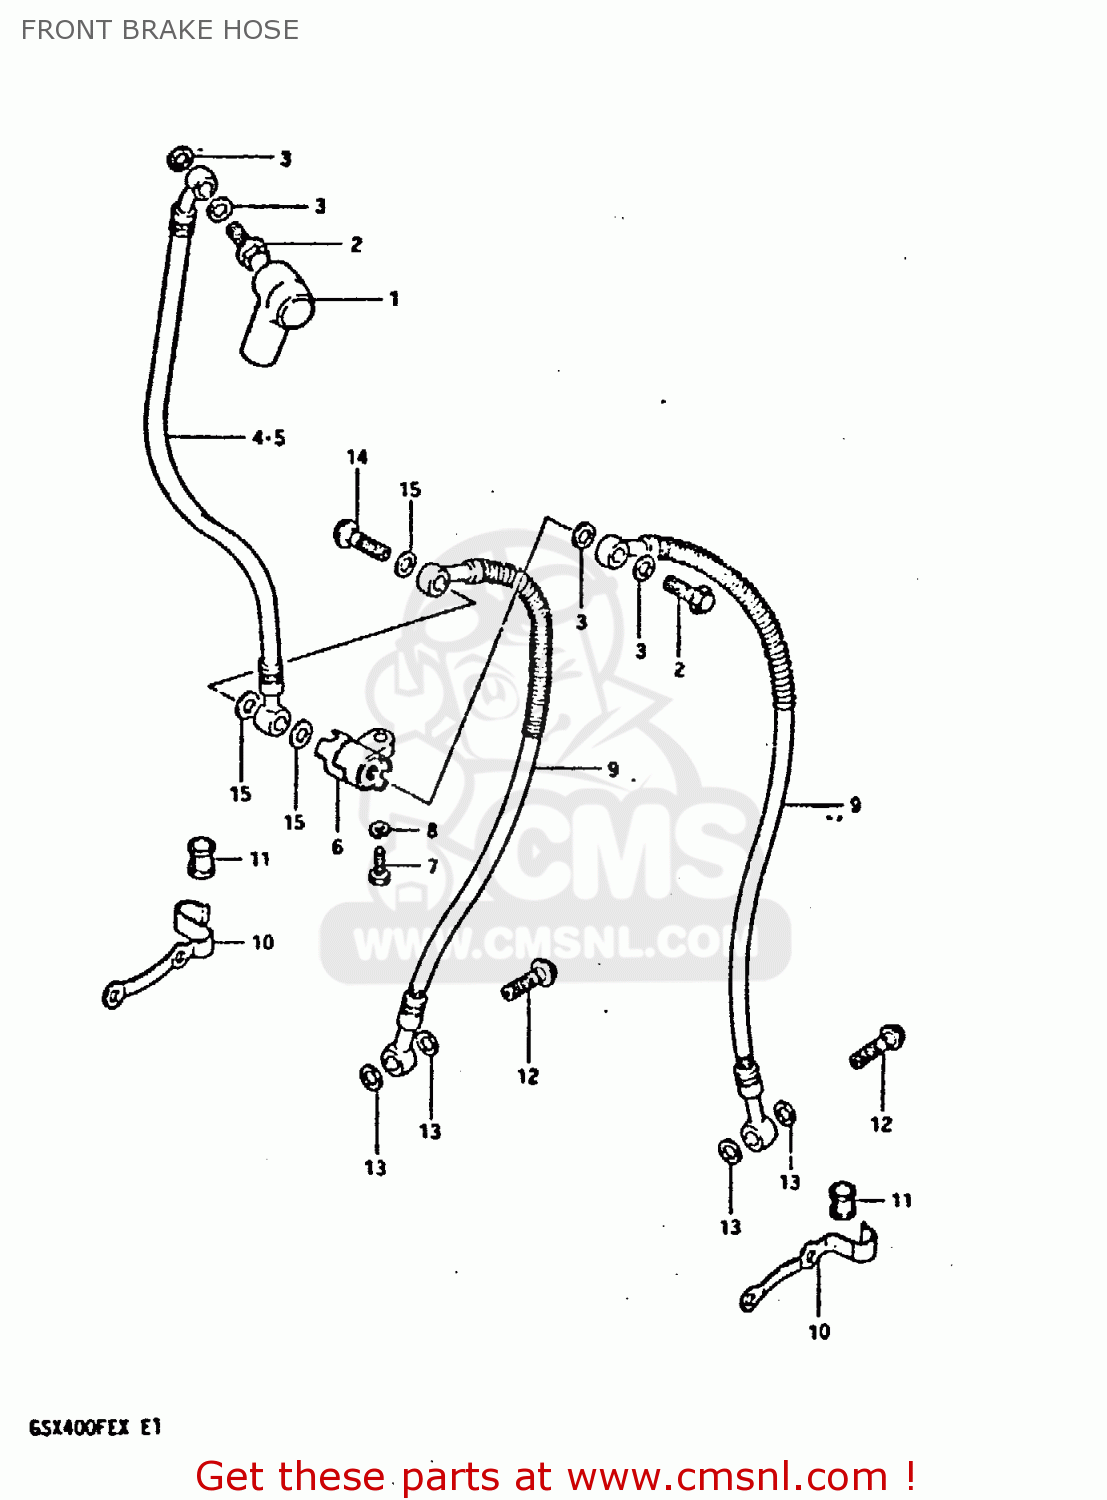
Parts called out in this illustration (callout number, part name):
1	BOOT,MASTER CYLINDER
2	BOLT,UNION
3	WASHER
4	HOSE, BRAKE NO.1 (FOR NEUTRAL HANDLEBAR)
5	HOSE,FRONT BRAKE
6	JOINT,BRAKE HOSE
7	BOLT
8	LOCK WASHER
9	HOSE,BRAKE NO.2
10	GUIDE,BRAKE HOSE NO.2
11	BUSH,BRAKE HOSE GUIDE,NO.2
12	BOLT,UNION
13	WASHER
14	BOLT,UNION
15	WASHER
